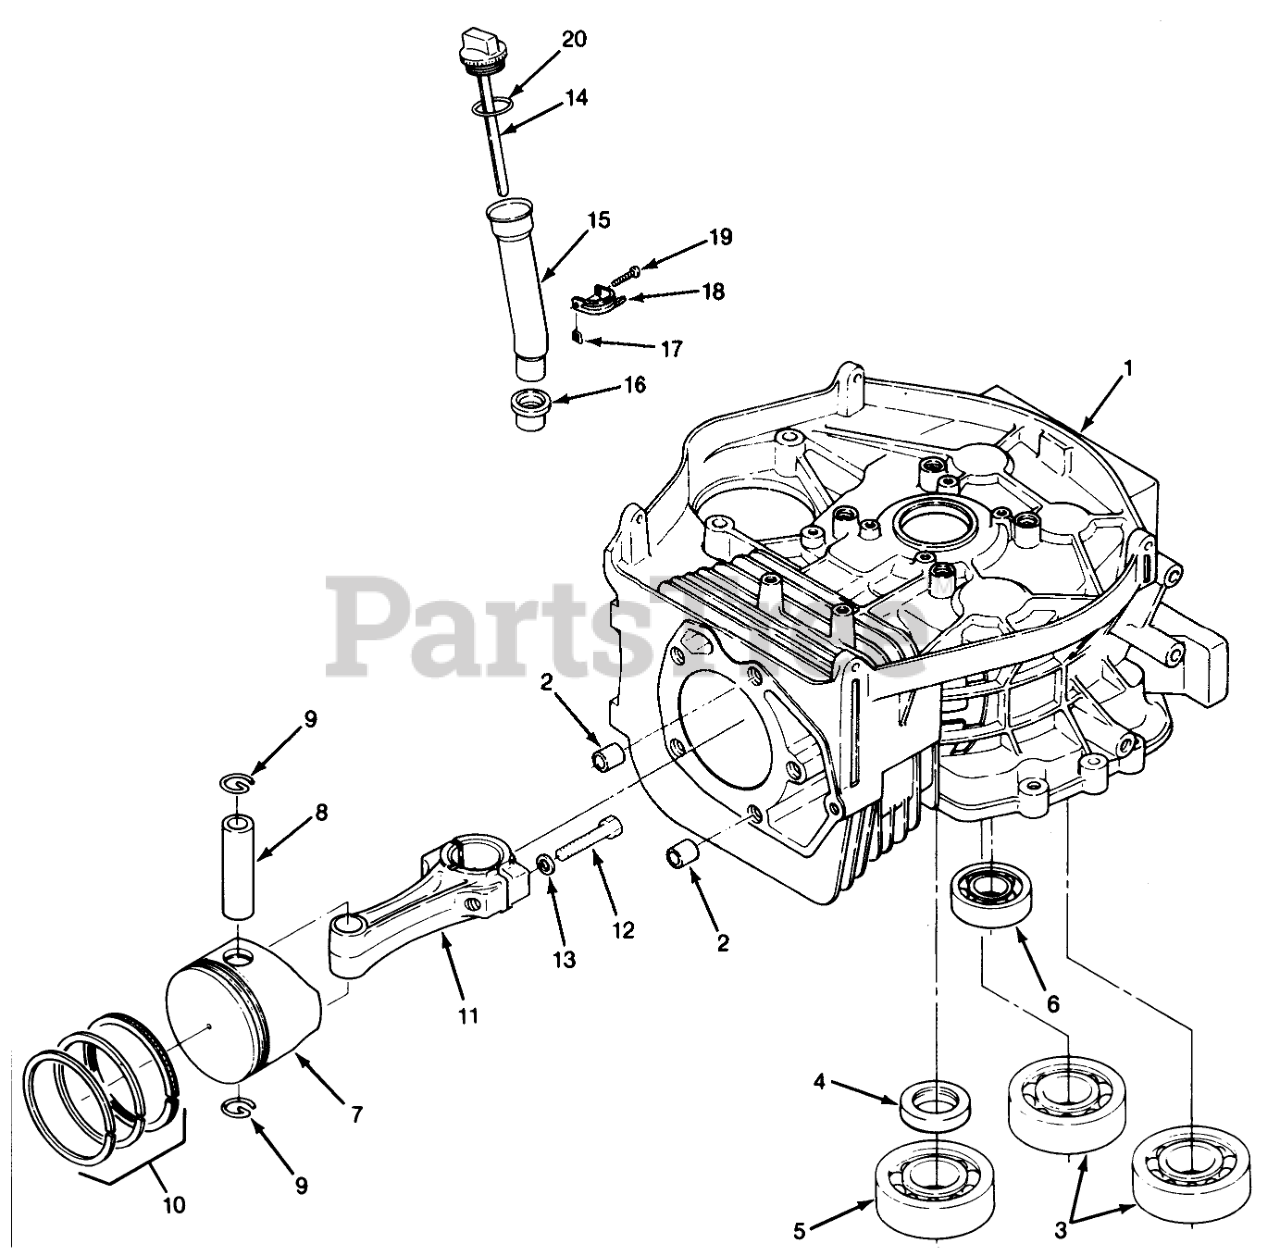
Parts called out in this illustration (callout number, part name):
1	BLOCK-CYLINDER
2	Dowel Pin
3	Ball Bearing
4	SEAL-OIL CRNKSHFT UP
5	BEARING-BALL CRANKSH
6	BEARING-BALL CAMSHFT
7	Kit-Piston (Standard) (Incl. Ref. #8-9)
8	PIN-PISTON
9	RING-RETAINING
10	Piston Ring Set-Standard
11	Kit-Connecting Rod (Standard) (Incl. Ref. #12-13)
12	Bolt
13	WASHER-CONN ROD
14	INDICATOR
16	Seal
17	Nut
18	BRACKET
19	Screw
20	O-Ring
